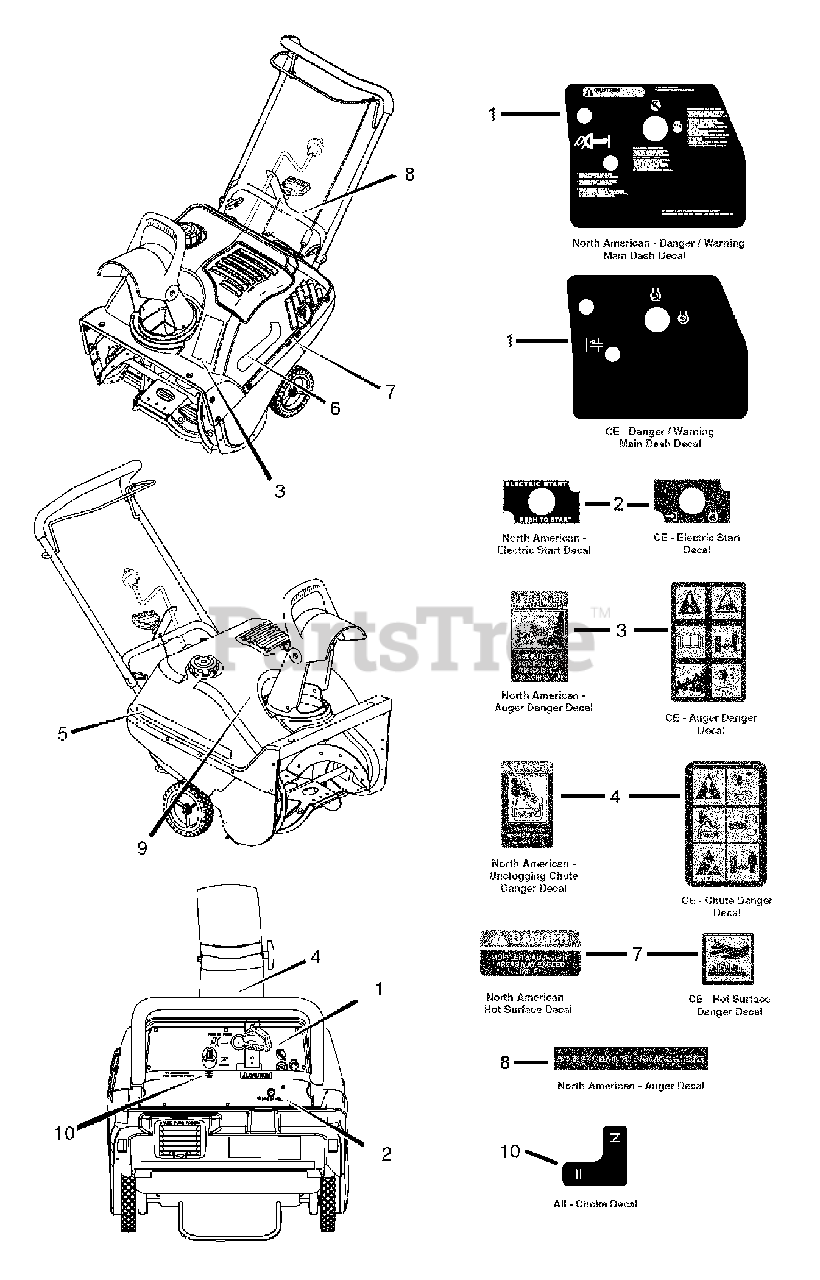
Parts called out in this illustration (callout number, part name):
1	DECAL, Control Panel English 22"
1	DECAL, Control Panel
2	DECAL, Electric Start
3	DECAL, Danger Auger
3	DECAL, Auger Engine
4	DECAL, Danger Chute
5	DECAL, Snapper ST0522 R.H.
5	DECAL, Snapper SS522EX Right Hand
6	DECAL, Snapper ST0522 L.H.
7	DECAL, Hot Muffler
7	DECAL, Hot Surface
8	DECAL, Auger Control
9	DECAL, Briggs & Stratton
10	DECAL, Choke
